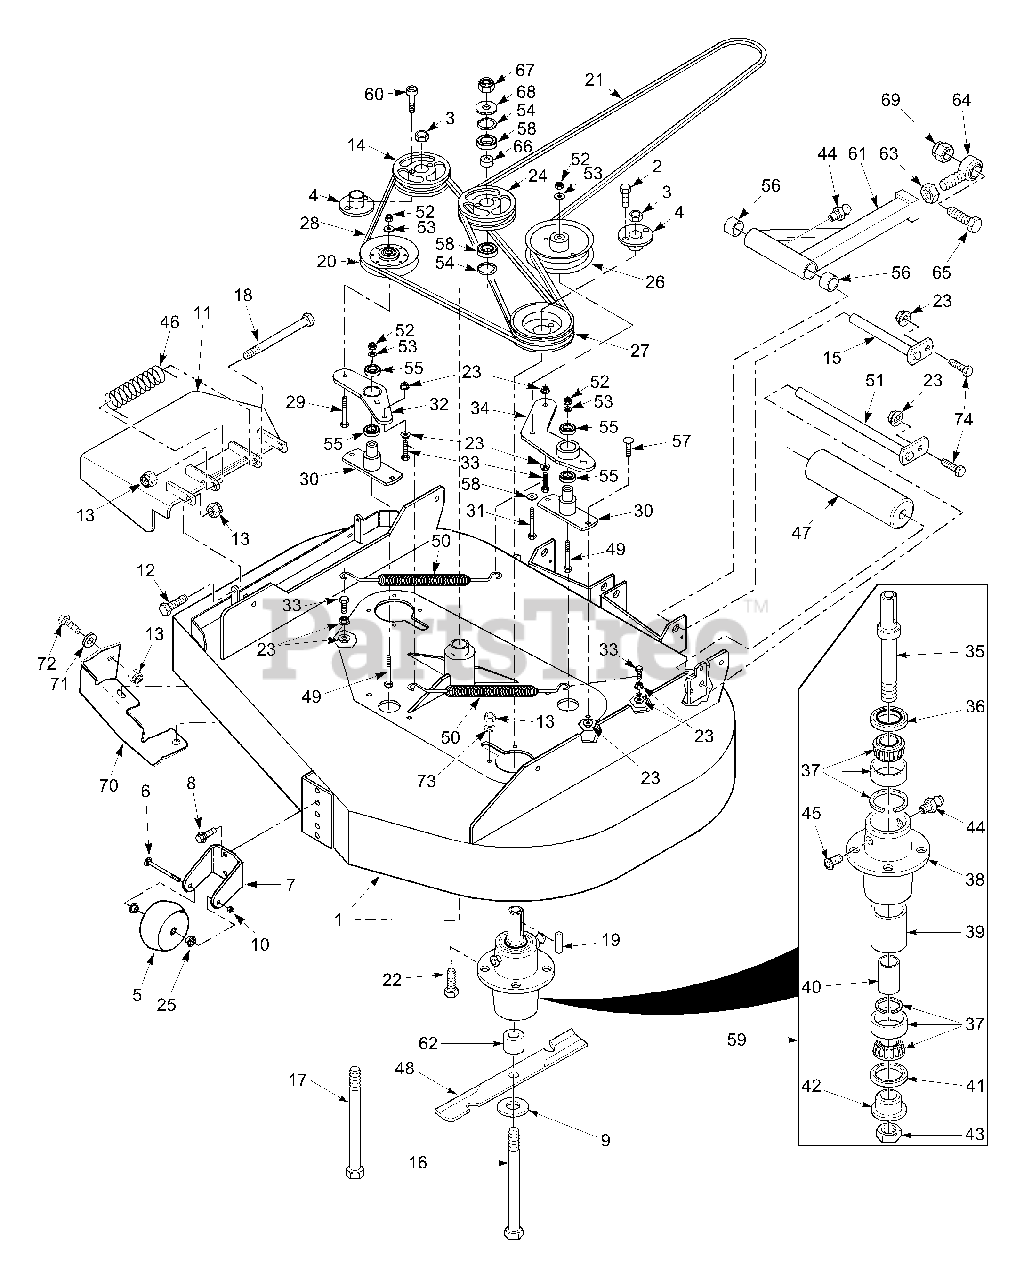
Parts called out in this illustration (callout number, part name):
1	Cutter Deck
2	Bolt, Hex Head 1/2-20 x 3/4"
3	Nut, 5/8-11 UNC
4	Hub, Tapered 1-1/8" Bore
5	Anti-Scalp Wheel
6	Bolt, Carriage 3/8-16 x 4"
7	Bracket, Anti-Scalp Wheel
8	Bolt, Serrated Flange 3/8-16 x 1"
9	Flatwasher 5/8"
10	Locknut, 3/8-16 Center Lock
11	Discharge Chute
12	Bolt, Hex Head 5/16-18 x 1-1/2"
13	Nut, Elastic Stop 5/16-18
14	Pulley, Tapered Bore 5-3/4"
15	Push Arm Shaft
16	Bolt, Hex Head 5/8-11 x 9-1/2"
17	Bolt, Hex Head 1/2-13 x 5"
18	Bolt, Hex Head 5/16-18 x 4-3/4"
19	Key, 1/4 x 1/4 x 2"
20	Pulley, Idler
21	Belt, Cutter Deck Drive
22	Bolt, Hex Head 5/16-18 x 1-1/2"
23	Nut, Serr. Flange 5/16-18
24	Pulley, Idler - 5.75 Dia.
25	Bushing, .376 ID Oilite
26	Pulley, Idler 5"
27	Pulley, Double Groove 5-3/4"
28	Belt, RH Cutter Deck
29	Bolt, Hex Head 3/8-16 x 2"
30	Pivot, Idler Base
31	Bolt, Hex Head 3/8-16 x 3-1/4"
32	Idler Arm
33	Bolt, Hex Head 3/8-16 x 1-1/2" Grade 8
34	Idler Arm
35	Shaft, Spindle
36	Seal Upper
37	Bearing Assembly
38	Housing, Spindle
39	Spacer, Outside
40	Spacer, Inside
41	Seal, Lower
42	Bushing, Bottom
43	Nut, Special 1-1/16-18
44	Grease Fitting
45	Valve, Grease Relief
46	Spring, Discharge Chute
47	Roller Rear
48	Cutter Blade 20"
49	Bolt, Hex Head 3/8-16 x 2-1/2"
50	Spring, Idler
51	Shaft, Roller
52	Nut, 3/8-16 Elastic Stop
53	Flatwasher, 3/8-.391 x .938 x .105
54	Ret. Ring, 1.575 Internal
55	Bearing
56	Bearing, Bronze Oilite
57	Bolt, Carr. 5/16-18 x 1"
58	Bearing, Idler Pulley
59	Spindle Assembly
60	Socket Head Capscrew 1/4-20 x 1-3/8"
61	Push Arm
62	Spacer, Spindle
63	Nut, 5/8-18 UNF
64	Rod End, 5/8 Male RH Thread
65	Bolt, Hex Head 5/8-11 x 4-1/2"
66	Sleeve, Idler Pulley
67	Nut, Elastic Stop 1/2-13
68	Flatwasher, 1/2 SAE Hardened
69	Nut, Elastic Stop 5/8-11
70	Turbo Baffle, Bolt On
71	Flatwasher, 5/16"
72	Bolt, Hex Head 5/16-18 x 1"
73	Lockwasher, 5/16"
74	Bolt, Hex Head 5/16-18 x 1"
